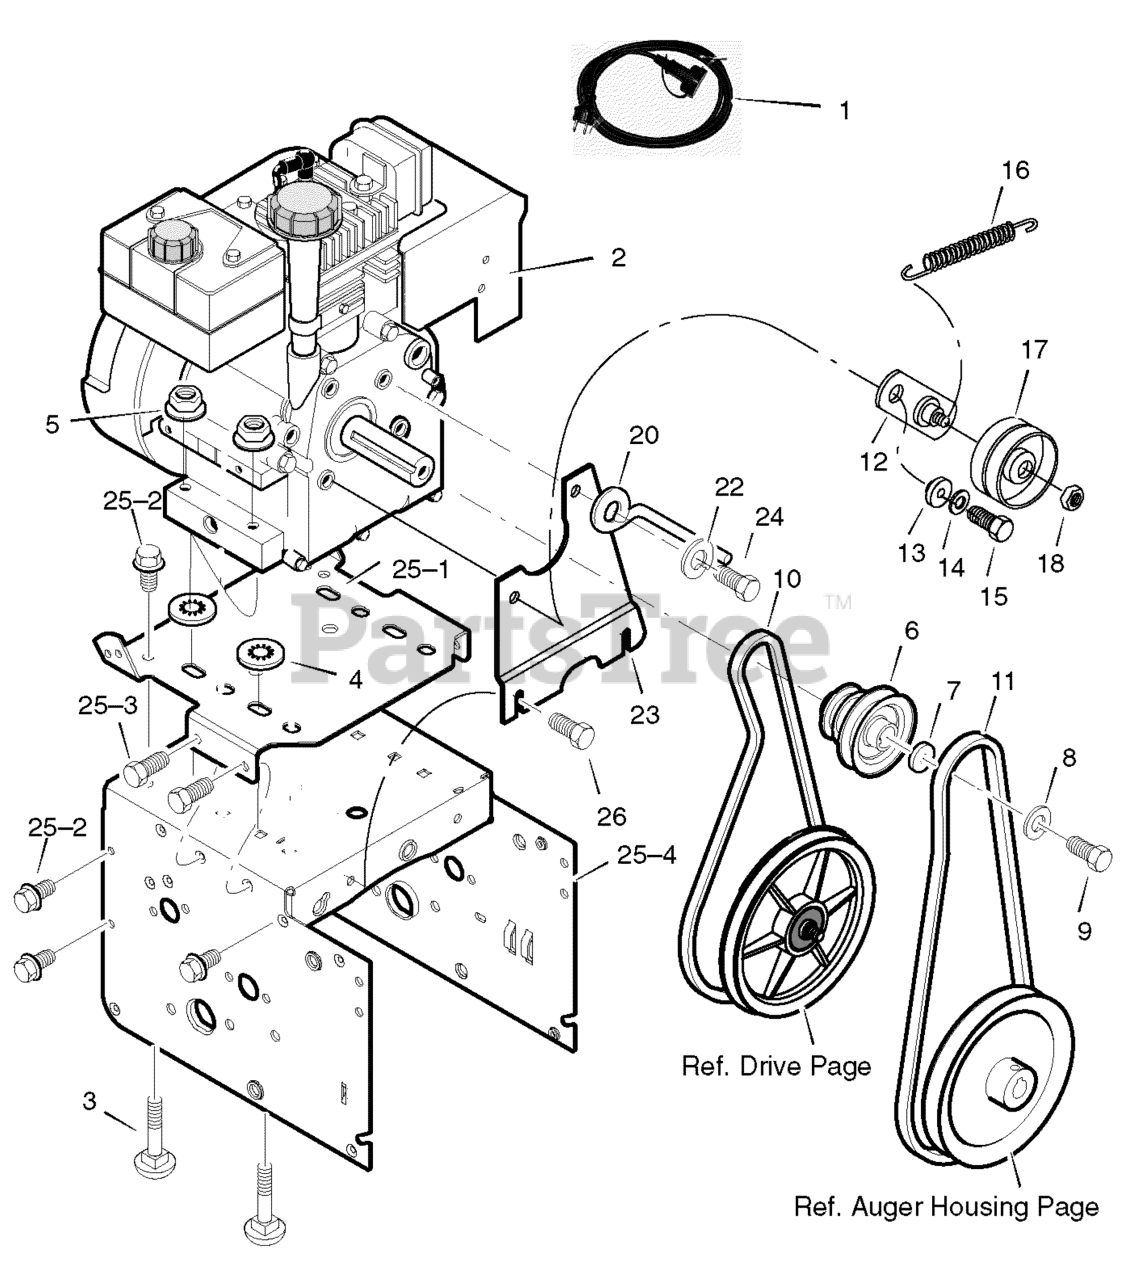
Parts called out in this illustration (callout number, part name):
1	CORD, STARTER
3	BOLT, CARRIAGE
4	RETAINER, PUSH
6	PULLEY, ENGINE
7	WASHER
8	WASHER .38ID
9	SCREW, 3/8-24 x 1.00
10	BELT, V 3L 33.13LG
11	BELT, V 4L 38.1MF16" 5-10
12	BRACKET ASSEMBLY, IDLER
13	BUSHING, IDLER BRACKET
14	WASHER, SPLIT
15	SCREW 5/16-24 X 1.00
16	SPRING, IDLER TRACTION DRIVE
17	PULLEY, IDLER
18	NUT, JAM 3/8-16
20	GUIDE, BELT
22	WASHER, SPTLK .31X.58X.08
23	PLATE, ANTI VIBRATION
24	SCREW, 5/16-24X 1.00
25	FRAME ASSEMBLY
25-1	PLATE, ENGINE MOUNT
25-2	SCREW, TAP 1/4-20 X .63
25-3	SCREW, TAP 5/16-18 X .50
25-4	FRAME, MOTOR BOX
26	SCREW
